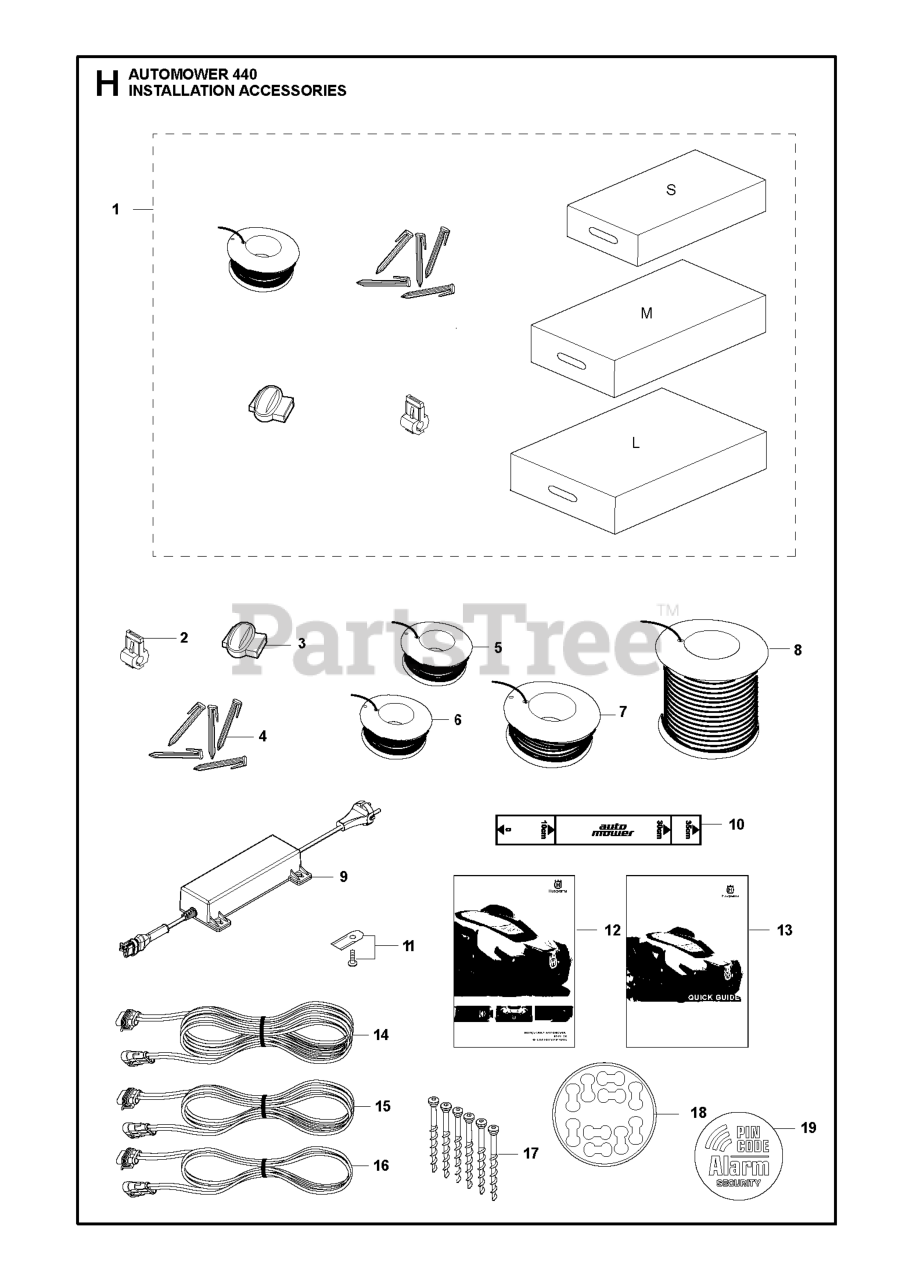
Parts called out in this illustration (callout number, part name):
1	SMALL AUTOMOWER INSTALL KIT
1	MED AUTOMOWER INSTALL KIT
1	LARGE AUTOMOWER INSTALL KIT
2	BRAKER
2	CONNECTOR 5 PCS, BLISTER
3	COUPLER SPLICER, 5 PCS,
3	COUPLER SPLICER, 100 PCS
3	SPLICE KIT
4	STAPLE 100 PCS
4	STAPLE 100 PCS, BLISTER
5	WIRE 150M, BLISTER
5	WIRE 50M STANDARD Ø2.7MM,BLIST
5	WIRE BOUNDARY 150M
6	WIRE 250M
7	WIRE 500M
8	WIRE (800M)
9	POWER UNIT POWER SUPPLY UNIT 7
10	RULER / CENTIMETERS
11	HUS BLADE SET 9 PCS
11	HUS BLADE SET 45 PCS
11	HUS BLADE SET 300 PCS
14	CABLE LOW VOLTAGE CABLE P2 5-7
15	CABLE LOW VOLTAGE CABLE P2 5-7
16	CABLE LOW VOLTAGE CABLE P2 5-7
17	SCREW 3 PCS, BLISTER PACK
17	SCREW KIT CS
18	STICKER CABLE MARKERS KIT 10PC
19	LABEL SECURITY
